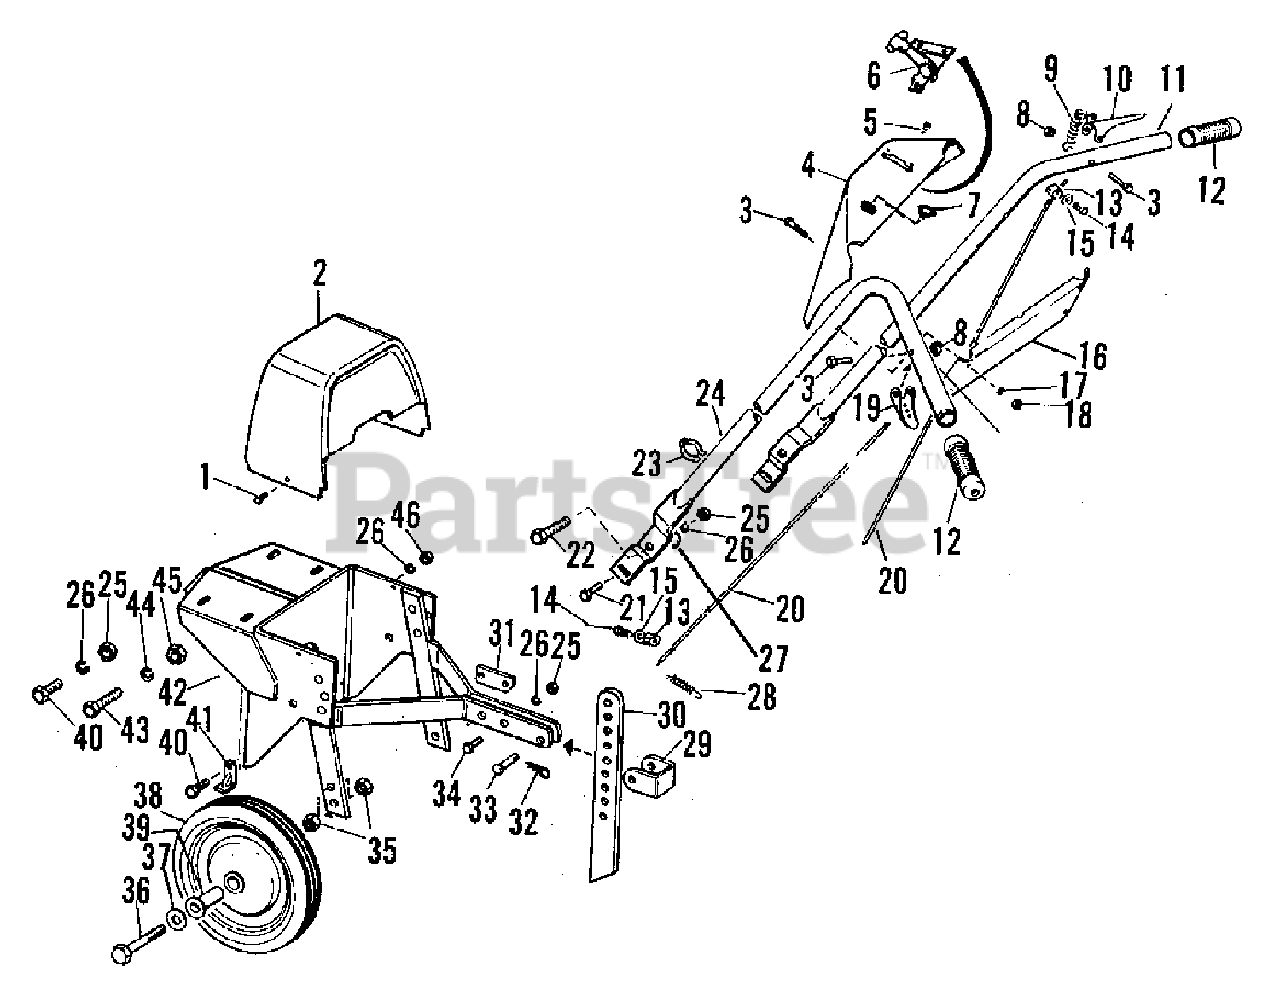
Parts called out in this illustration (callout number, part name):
1	SCREW, Hex, 1/4-20 x 3/8
3	SCREW, Hex, Cap, 1/4-20 x 1-1/2
4	HOUSING, Control
5	SCREW, Hex, 1/4-20 x 1/2
6	CONTROL, Throttle
7	PLUG, Button
8	NUT, Hex, 1/4-20
10	GRIP, Clutch (Forward)
11	HANDLE, R.H.
12	GRIP, Handle Bar
14	SCREW, Set Square, 10-24 x 5/8
15	WASHER, Flat, 3/16
16	COVER, Handle Bar
17	WASHER, Lock, 1/4
18	NUT, Hex, 1/4-20
19	GRIP, Clutch (Reverse)
21	SCREW, Hex, 3/8-16 x 1
22	SCREW, Hex, Cap, 3/8-16 x 1-1/4
24	HANDLE, L.H.
25	NUT, Hex, 3/8-16
26	WASHER, Lock, 3/8
27	WASHER, Flat, 3/8
32	CLIP, Spring
34	SCREW, Hex, Cap, 3/8-16 x 1-1/2
35	NUT, Hex, 1/2-13
36	SCREW, Hex, Cap, 1/2-13 x 3-1/4
37	WASHER, Flat
38	WHEEL & TIRE
39	BUSHING, Wheel
40	SCREW, Hex, Cap, 3/8-16 x 3/4
43	SCREW, Hex, Cap, 7/16-20 x 1-1/4
44	WASHER, Lock, 7/16
45	NUT, Hex, 7/16-20
46	NUT, Hex, 3/8-16
